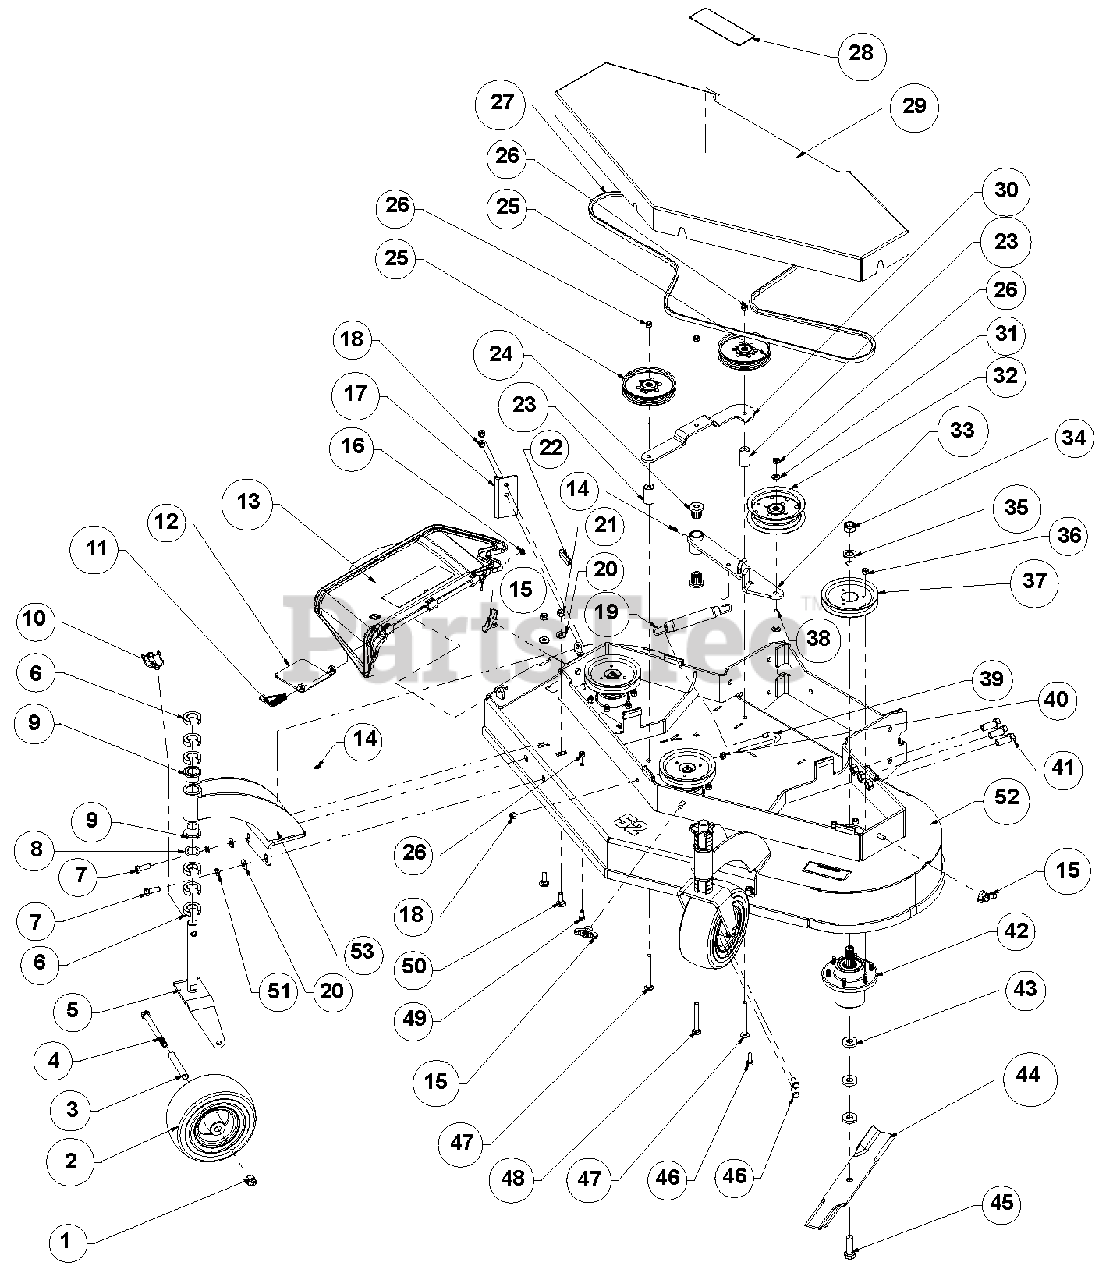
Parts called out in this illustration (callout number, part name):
1	Locknut, .50-13 Nyloc
2	Assembly, Wheel and Tire 9 x 3.5
3	Tube, Caster Axle
4	Bolt, .50-13 x 5.50 Hex 5
5	Weldment, Caster Yoke w/EverRide Paint
6	C-Spacer, 1.00 x 1.77 x .500
7	Bolt, .4375-14 x 1.25 Hex 5
8	Bushing, 1.03 x 1.50 x .179
9	Bearing, Flange 1.00 x 1.25 x 1.00
10	Pin, LNC .438 x 2.00
11	Spring, Discharge Chute
12	Bracket, Chute Support
13	Chute, Discharge Assembly
14	Fitting, .25-28 Straight Grease Zerk
15	Knob, .38-16 Insert
16	Retainer
17	Plate, Extender
18	Locknut, 3/8-16 Nyloc
19	Spring, External
20	Washer, .375 Regular Flat
21	Locknut, .4375-14 Crown
22	Trim, 1/4" Trim-Lok Edge
23	Spacer Assembly
24	Bearing, Flange M10 x M25 x M27 Fluted
25	Pulley, Flat Idler
26	Locknut, .38-16 Crown
27	Belt, HB 109.3 Elbow AMD
28	Decal, Pro-1952
29	Weldment, 52" Belt Shield EverRide
30	Strap, Idler Pulley Hydro Walk
31	Washer, .406 x .813 x .065 Flat
32	Pulley, Flat 5.00 x .375 w/BRG
33	Arm, Idler
34	Locknut, .75-16 Crown
35	Washer, .75 x 1.3125 x .120
36	Nut, .38-16 Standard Hex 5
37	Pulley, Spline Spindle LSE
38	Bolt, .38-16 x 2.25 Round Head Square Neck
39	J-Bolt, .38-16 x 4.00
40	Locknut, .38-16 Whiz
41	Bolt, Hex .6250-11 1.5" Grade 8
42	Assembly, Spindle Housing
43	Washer, .630 x 1.50 x .250 Flat
44	Blade, 18.000 x .80 Lift
45	Bolt, .625-11 x 2.00 Hex 8
46	Bolt, .38-16 x 1.00 Hex 5
47	Bolt, .3750 x 4 SHTNK Round Head Bolt
48	Bolt, .38-16 x 3.50 Round Head Square Neck
49	Bolt, .38-16 x .750 Hex 5
50	Bolt, .4375-14 x 1.25 Round Head Square Neck
51	Washer, .438 Medium Spring Lock
52	Assembly, 52" EverRide Deck w/Decals
53	Weldment, Caster Support w/EverRide Paint
